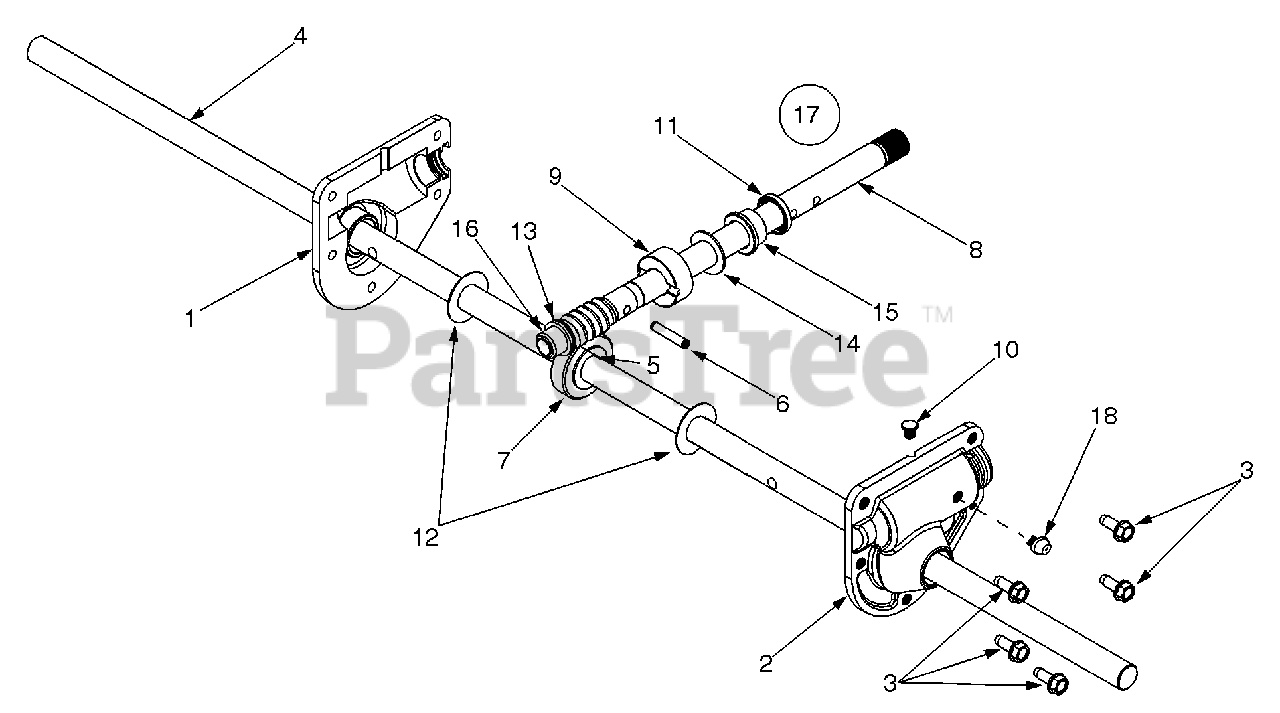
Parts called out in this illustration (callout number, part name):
1	RH Housing
2	LH Housing w/Fitting
3	Self Tapping Screw, 1/4-20 x .75
4	Spiral Axle, 26"
5	Hi-Pro Key, 3/16 x 5/8
6	Spring Spiral Pin, .25 x 1.25
7	Worm Gear, 20-tooth
8	Worm Shaft
9	Thrust Collar
10	Grease Plug
11	Grease Seal
12	Flat Washer, .76 x 1.5 x .030
13	Flat Washer, .508 x 1.0 x .020
14	Flat Washer, .76 x 1.5 x .060
15	Flange Bearing, .75 x 1.0 x .59
16	Flange Bearing, .503 ID x .75 OD
17	Gear Ass'y Complete, 26"
18	Grease Fitting, 3/16" Drive
